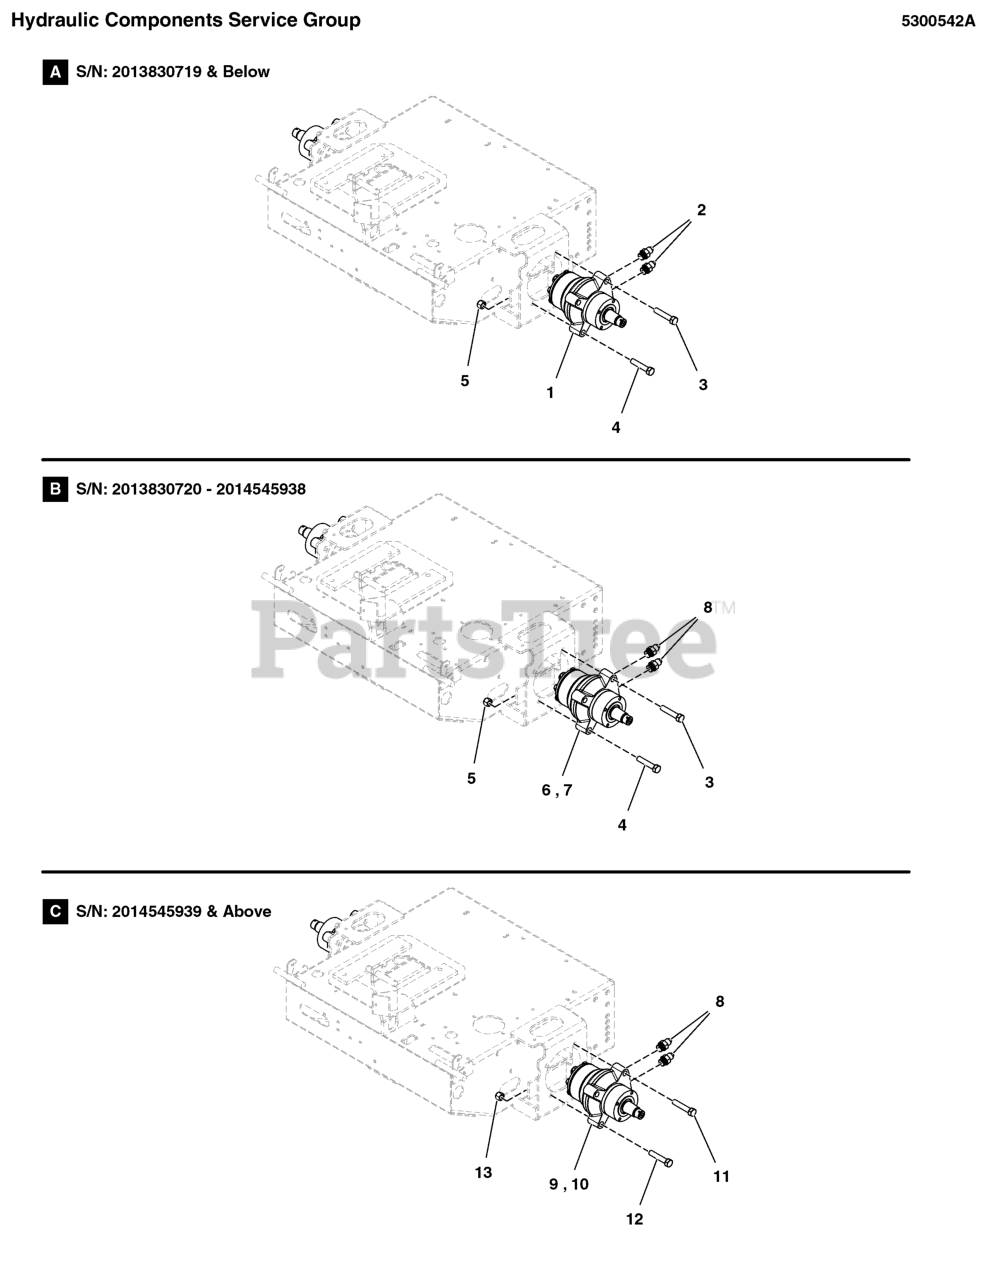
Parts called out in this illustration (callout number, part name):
2	FITTING, #8 O-RING X #8 JIC, STR
3	BOLT, 1/2-20 X 2-1/2" GD5 CZ
4	BOLT, 1/2-20 X 3 GD8 YZ
5	NUT, Hex, Nylon Lock, 1/2-20
8	FITTING, #10 O-RING X #8 JIC, STR
9	WHEEL MOTOR, LH, 11.9 CI SHORT
10	WHEEL MOTOR, RH, 11.9 CI SHORT
11	BOLT, 1/2-13 X 3, DRI-LOC PATCH
12	BOLT, 1/2-13 X 3.5, DRI-LOC PATCH
13	NUT, 1/2-13 SQUARE
